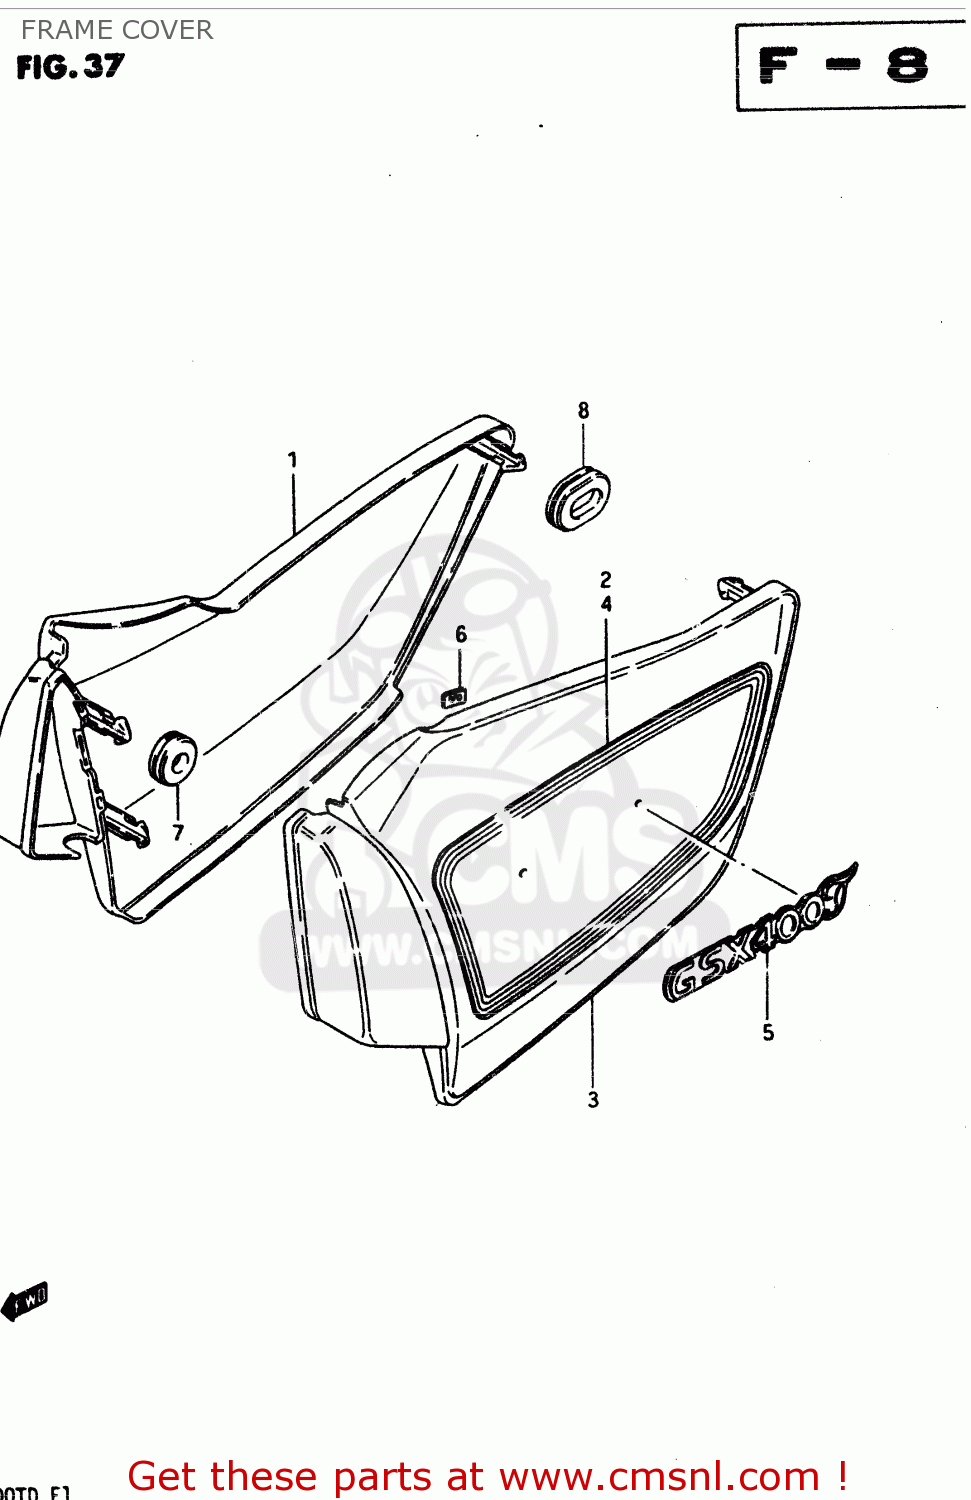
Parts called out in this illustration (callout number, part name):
1	COVER,FRAME,RIGHT
2	TAPE SET,FRAME COVER
3	COVER,FRAME,LEFT
4	TAPE SET,FRAME COVER
5	EMBLEM
6	NUT
7	CUSHION
8	CUSHION, REAR
